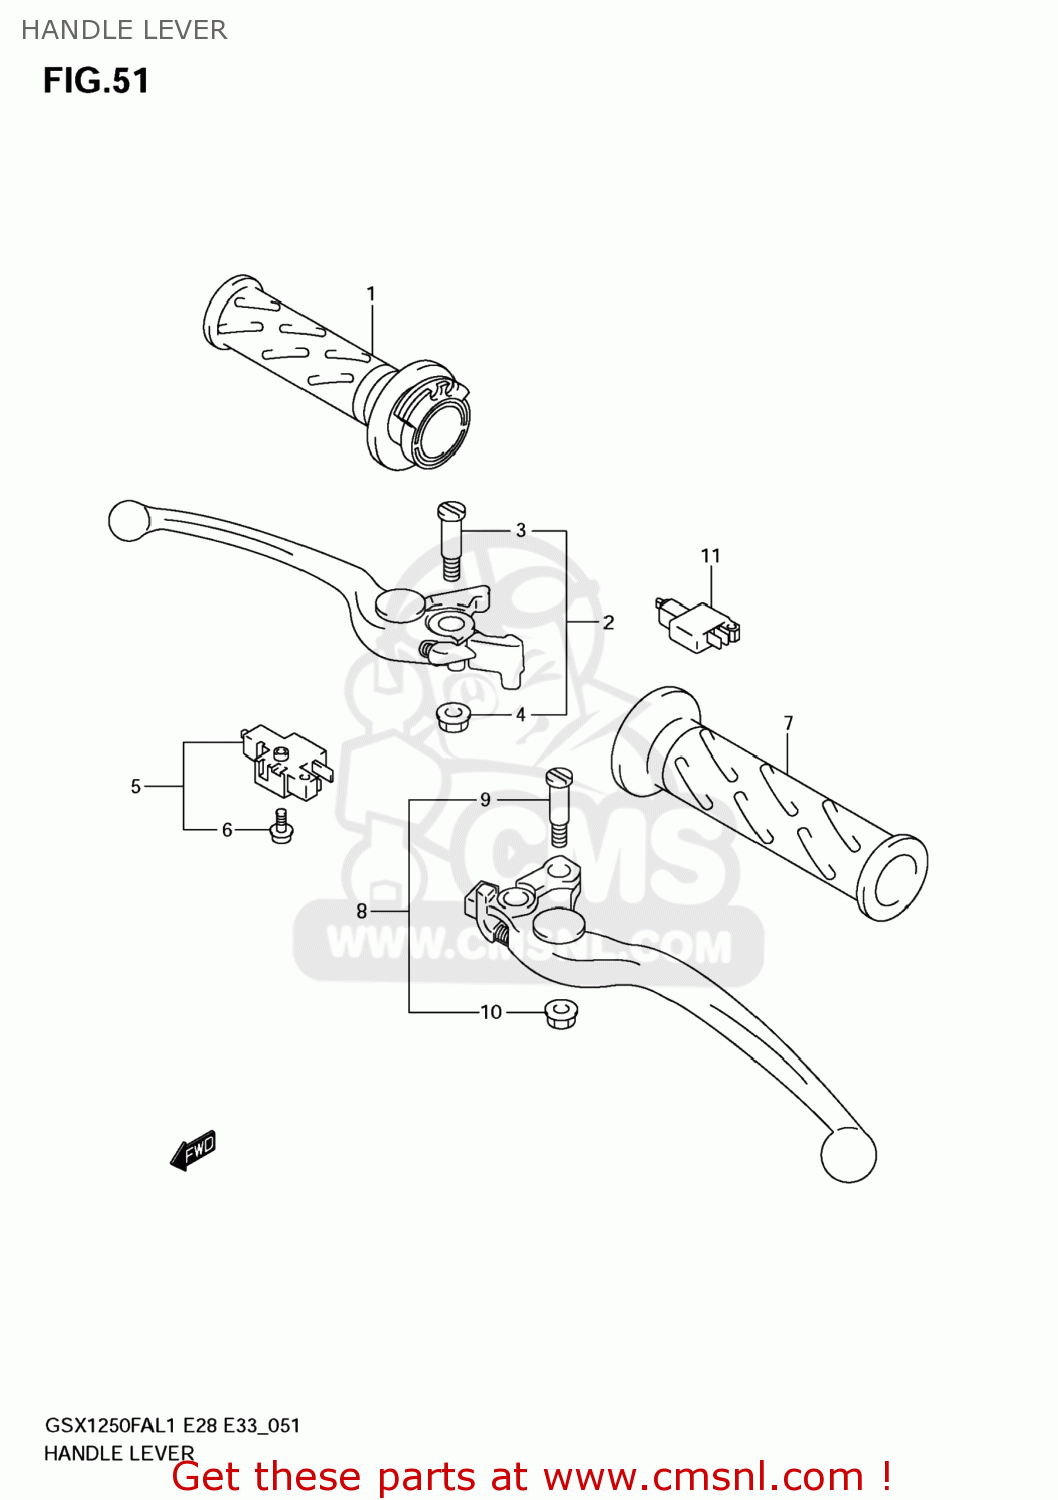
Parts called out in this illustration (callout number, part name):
1	GRIP,THROTTLE(BLACK)
2	LEVER ASSY,FR
3	BOLT,LEVER PIV
4	NUT
5	SWITCH ASSY,ST
6	SCREW
7	GRIP,L
8	LEVER ASSY,CLU
9	BOLT,LEVER PIV
10	NUT
11	SWITCH ASSY,CLUTCH
